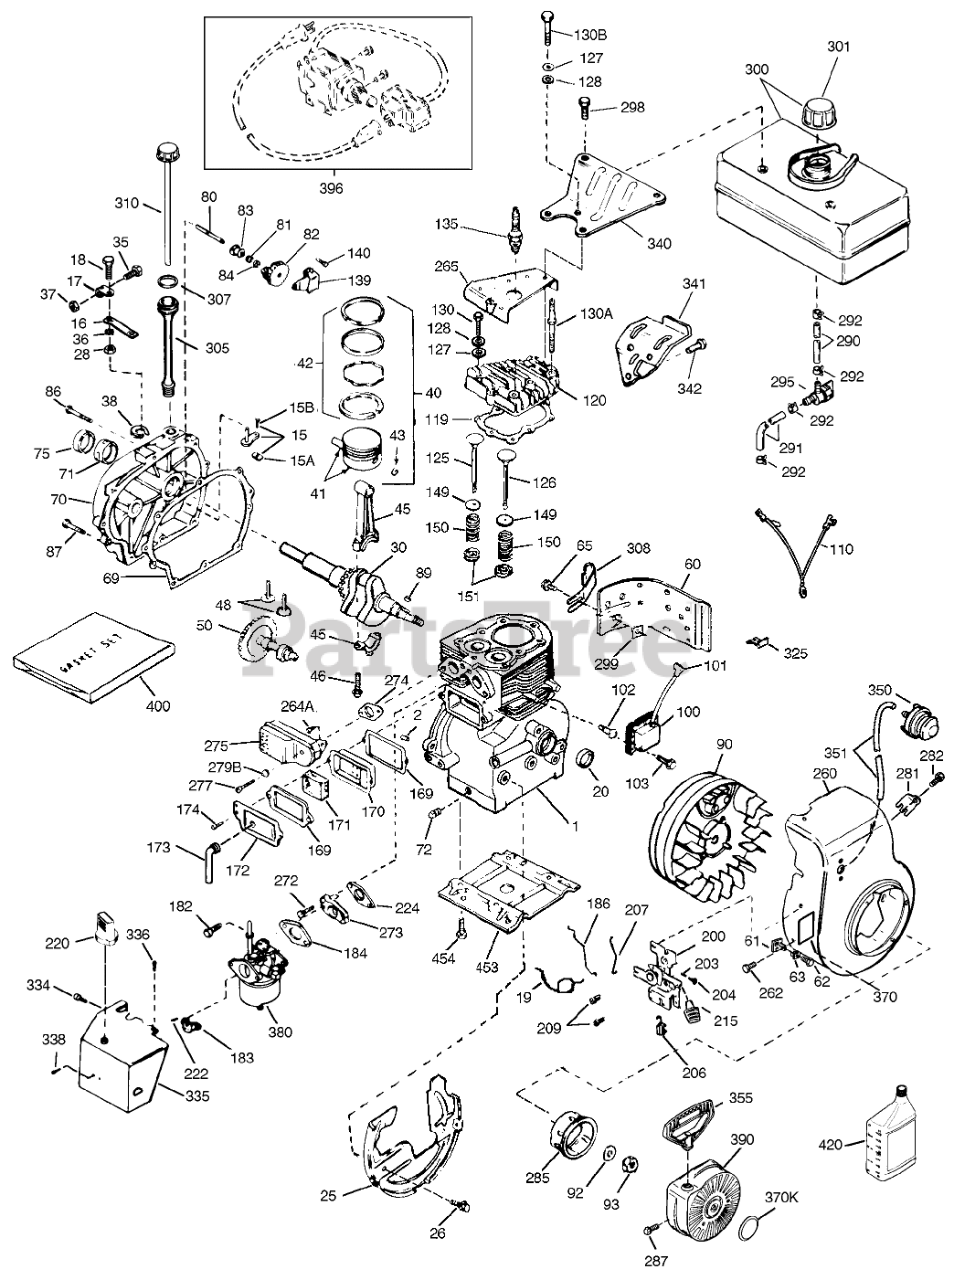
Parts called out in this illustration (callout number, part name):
1	Cylinder (Incl. Ref. #2,20 & 72)
2	Pin-Dowel
15	Governor Rod (Incl. Ref. #15A & 15B)
15A	Yoke-Governor
15B	Screw (6-40x5/16)
16	Lever-Governor
17	Clamp-Lever, Governor
18	Screw
19	Spring-Throttle
20	Oil Seal
25	Baffle-Housing, Blower
26	Screw (1/4-20x19/32)
28	Nut-Lock
30	Crankshaft
36	Washer-Lock
37	Nut-Lock
38	Ring-Retaining
40	Piston, Pin & Ring Set (Std.)
40	Piston, Pin & Ring Set (.010" OS)
41	Piston & Pin Assembly (Std.) (Incl. #20)
41	Piston & Pin Ass-y (.020" OS)(Incl. Ref. #43)
41	Piston & Pin Ass-y (Std.)(Incl. Ref. #43)
42	Ring Set (Std.)
42	Mudguard R.H.
42	Mudguard L.H.
43	Ring-Retaining, Piston Pin
45	Connecting Rod Ass-y (Incl. Ref. #46 & 49)
46	Bolt-Connecting Rod
48	Lifter-Valve
49	Dipper-Oil
50	55012A GIL SNWTHWR
60	Extension-Blower Hsng.
61	Bracket
62	Screw (8-32 x 3/8)
63	Grommet
69	Gasket-Cover, Cylinder
70	Cylinder Cover (Incl. Ref. #71, 75, & 80)
71	Bushing-Crankshaft
72	Plug-Drain, Oil (SQH 1/4-18)
75	Oil Seal
80	Shaft-Governor
81	Washer-Flat
82	Governor Gear ASM
83	Spool-Governor
84	Ring-Retaining
86	Screw (1/4-20 x 1-1/4)
89	Key-Flywheel
90	Flywheel
92	Washer-Belleville
100	Solid State
101	Cover-Spark Plug
102	Stud
103	Screw (T-15, 10-24 x 15/16)
110	Ground Wire
119	Cylinder Head Gasket
120	Cylinder Head (Incl. 3 of 131)
125	Exhaust Valve (Std.)(Incl. Ref. #151)
125	Exhaust Valve (1/32" OS)(Incl. Ref. #151)
126	Intake Valve (1/32" OS)(Incl. Ref. #151)
126	Intake Valve (Std.)(Incl. Ref. #151)
127	Washer-Flat
128	Washer-Belleville
129	Screw (5/16-18 X 2-1/2)
130	Screw (5/16-18 X 2-1/2)
131	Screw (5/16-18 X 2-1/2)
135	Spark Plug-Resistor (R J19 L M)
139	Bracket, Governor
140	Screw, Torx T-25
149	Cap-Spring, Valve
150	Spring-Valve
151	Keeper-Spring, Valve
169	Gasket-Cover, Valve
170	Body-Breather
171	Element-Breather
172	Cover-Valve
173	Tube-Breather
182	Screw (T-30, 1/4-20 X 27-32)
183	Bracket-Choke
184	Gasket-Carburetor
186	Governor Link
200	Control Bracket (Incl. Ref. #203, 204, & 206)
203	Spring-Compression
204	Screw
206	Terminal
207	Link-Throttle
209	Screw (10-32 x 1/2)
215	Knob-Control
220	Knob-Choke
222	Screw (10-32 x 1/2)
224	Gasket-Pipe, Intake
260	Blower Housing
265	Cover-Head, Cylinder
273	481-1279 SENATOR RO
274	Gasket-Exhaust
275	Muffler
277	Screw (5/16-18 X 2)
282	Screw (8-32 x 3/8)
285	Starter Cup
287	Screw (8-32 x 21/64)
290	Line-Fuel (8.62)
291	Line-Fuel
292	Clamp-Line, Fuel
295	Valve-Shut Off, Fuel
298	Screw (1/4-15x7/8)
299	Nut-U Type
300	Fuel Tank (Incl. Ref. #292 & 301)
301	Cap-Fuel
305	Tube-Fill, Oil
308	Clip-Tube, Fill
310	Gauge Oil ASM
325	Clip-Wire
334	Screw (8-32 X 5/16)
335	Carburetor Cover
336	Screw (10-32x1/2)
338	Screw (8-32 x 3/8)
340	Bracket-Fuel Tank
341	Bracket-Fuel Tank
342	Screw (1/4-20x19/32)
350	Primer-Asm
351	Line-Primer
355	Handle-Starter, Mitten Grip
370	Decal-Lubrication
370K	Decal-Tecumseh Logo for Top of Recoil Starter
380	Carburetor (Incl. Ref. #184)
390	Starter-Rewind
396	Electric Starter Motor (110 Volt)
400	Gasket Set
420	4 Cycle Oil, SAE 30 (Quart)
453	Engine Mounting Base
